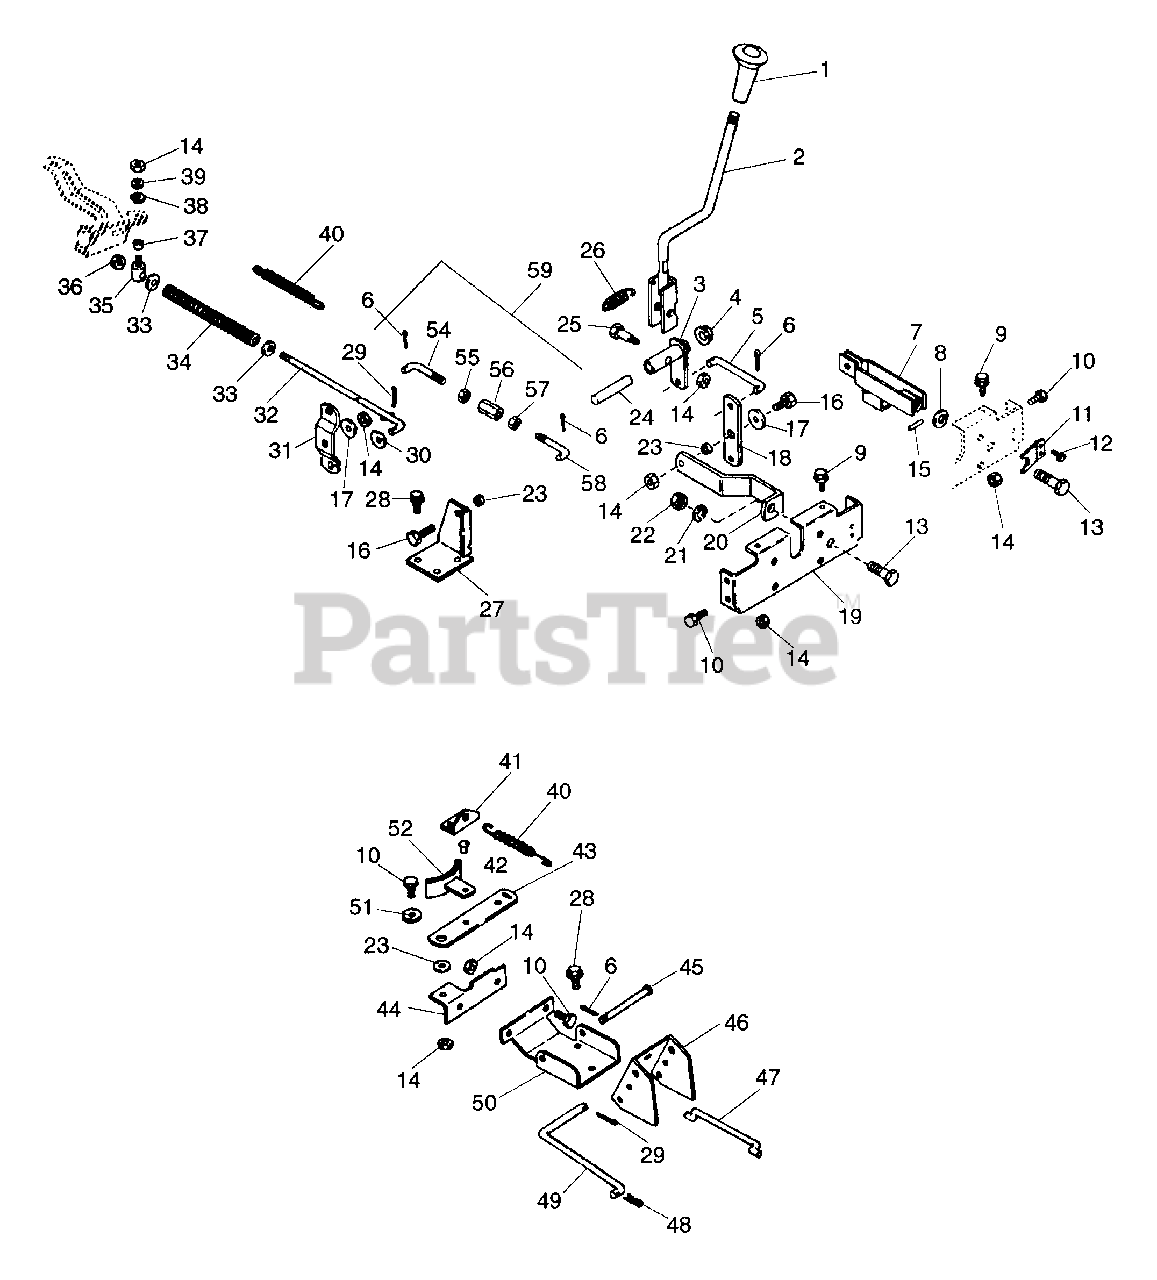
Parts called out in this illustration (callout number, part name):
2	MOWER CLUTCH LEVER
3	CLUTCH ARM
4	FLANGE BUSHING
5	LINK
6	PIN-COTR .09X.75 PL
7	ADJUSTMENT YOKE
8	WSHR-FL-STL .505X1.000X.062
9	SCR-TAP .250-20X.50 HXSLHDPL
10	BLT-HEX .31-18X.63 PL GR 2
11	LOCK SPRING
12	SCR-TAP 10-24X.25 CRSLPH PL 1A
13	CAP SCREW
13	BLT-HEX .50-13X1.25 PL GR2
14	NUT-LK .312-18 GR A PL
15	PIN-ROLL .188X1.00
16	BLT-HEX .31-18X.88 PL GR2
17	WSHR-FL-STL .344X1.125X.063PL
18	CLUTCH LINK
19	MOWER ADJUSTMENT BRACKET
20	FRONT ANCHOR
21	WSHR-LK .500X.151 HVY PL
22	NUT .50-13 PL
23	SPACER BUSHING .5 X .32 X .163
25	SHOULDER BOLT .436 X .912
26	SG-TENS .092X.69X1.75 WLD 54
27	DECK PIVOT BRACKET
28	SCR-TAP .312-18X.50 HWH PL TR
29	PIN-COTR .12X.75 PL
30	WSHR-FL-STL.344X.688X.065PL
31	ARM
32	CLUTCH ROD
33	WSHR-FL-STL .38X.875X.083 PL
34	SG-COMP .148X.68X6.5 WLD 90
35	ROD PIVOT
36	NUT-LK-CTR .375-16 GR A PL
37	SPACER BUSHING .5 X .32 X .21
38	WAVE WASHER .531X.781X.125FH
39	WSHR-FL-STL .323X.625X.062 PL
40	SG-TENS .072X.51X5.31 WLD 25
41	BRAKE CLIP
42	RVT .25X.50 RH ST
43	MOWER BRAKE LEVER
44	BRAKE BRACKET
45	PIN-CLEV .309X3.50 SP
46	MOWER ENGAGING ARM
47	MOWER BRAKE LINK
47	MOWER BRAKE LINK SERVICE ASSY
48	PIN-HAIR INT .08X.38X1.42 YWZC
49	MOWER ENGAGEMENT LINK
50	PIVOT BRACKET
51	WSHR-FL-STL .328X1.0X.094
52	BLADE BRAKE
53	SCR-TAP .250-20X.37 HWH PL TR
54	CLUTCH ROD RH
55	NUT-HEX .375-16
56	NUT-CUPLG RH & LH THD .37-16PL
57	NUT LH THD .375-16 GR 2 PL
58	CLUTCH ROD LH
59	CLUTCH ROD SERVICE ASSY
